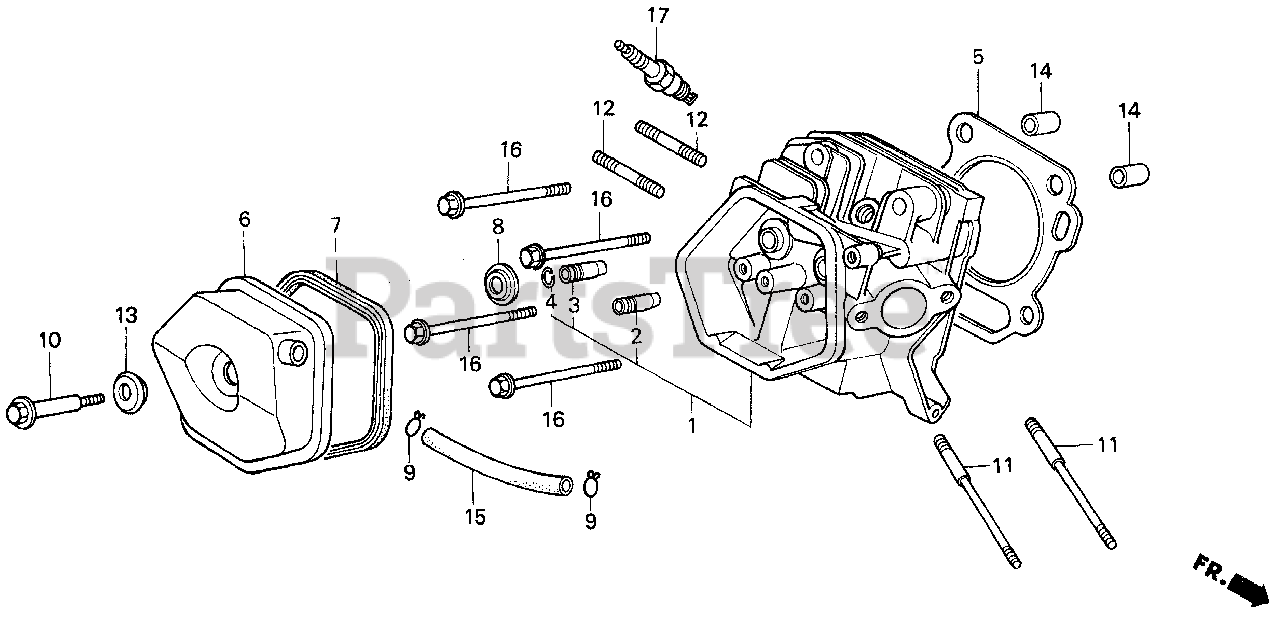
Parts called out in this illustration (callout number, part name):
1	CYLINDER HEAD
2	GUIDE, VALVE (OS)
3	GUIDE, EX. VALVE (OS)
4	CLIP, VALVE GUIDE
5	GASKET, CYLINDER HEAD
6	COVER, HEAD
7	GASKET, CYLINDER HEAD COVER
8	SEAT, VALVE SPRING
10	BOLT, HEAD COVER
11	BOLT, STUD (8X123)
12	BOLT, STUD (8X47)
12	BOLT 2, STUD (8X32)
13	WASHER, HEAD COVER
14	PIN A, DOWEL (12X20)
15	BULK HOSE, VACUUM (11X1000) (11X100)
15	BULK HOSE, VACUUM (11X1000) (11X105)
16	BOLT, FLANGE (10X80)
17	SPARK PLUG (BPR5ES) (NGK)
17	SPARK PLUG (W16EPR-U) (DENSO)
17	SPARK PLUG (BPR6ES) (NGK)
17	SPARK PLUG (W20EPR-U) (DENSO)
